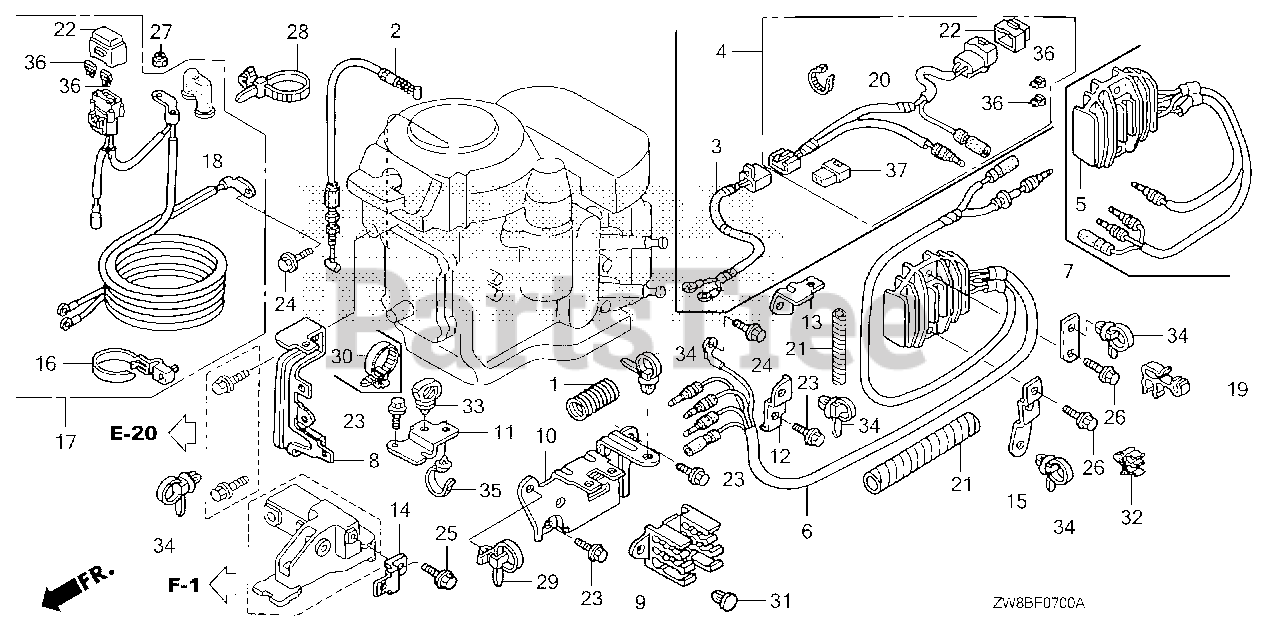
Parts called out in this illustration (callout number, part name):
2	CABLE, NEUTRAL STARTING
3	WIRE ASSY., BATTERY CHARGE
4	RECEPTACLE ASSY., CHARGE
5	RECTIFIER ASSY., REGULATOR
7	BRACKET, CLIP F
8	BRACKET, CONNECTOR A
9	BRACKET, CONNECTOR (B)
10	BRACKET, CONNECTOR C
11	BRACKET, STARTER CABLE
12	BRACKET, CLIP B
13	BRACKET, FUSE CASE
14	BRACKET, CONNECTOR D
15	BRACKET, E-CLIP
19	CLAMP, DISTRIBUTOR WIRE
20	TIE, CABLE (2.4X92) (NATURAL)
21	TUBE, SPIRAL A
22	COVER ASSY., FUSE (20A)
23	BOLT, FLANGE (6X14) (CT200)
25	BOLT, FLANGE (6X12)
26	BOLT, FLANGE (6X26) (CT200)
29	STRAP, CABLE (118MM) (BLACK)
31	CLIP, ANCHOR
32	CLIP, FUEL TUBE
33	CLIP, HARNESS
34	CLIP, HARNESS BAND (151.5MM) (NATURAL)
36	FUSE, BLADE (20A)
37	CONNECTOR, DUMMY
